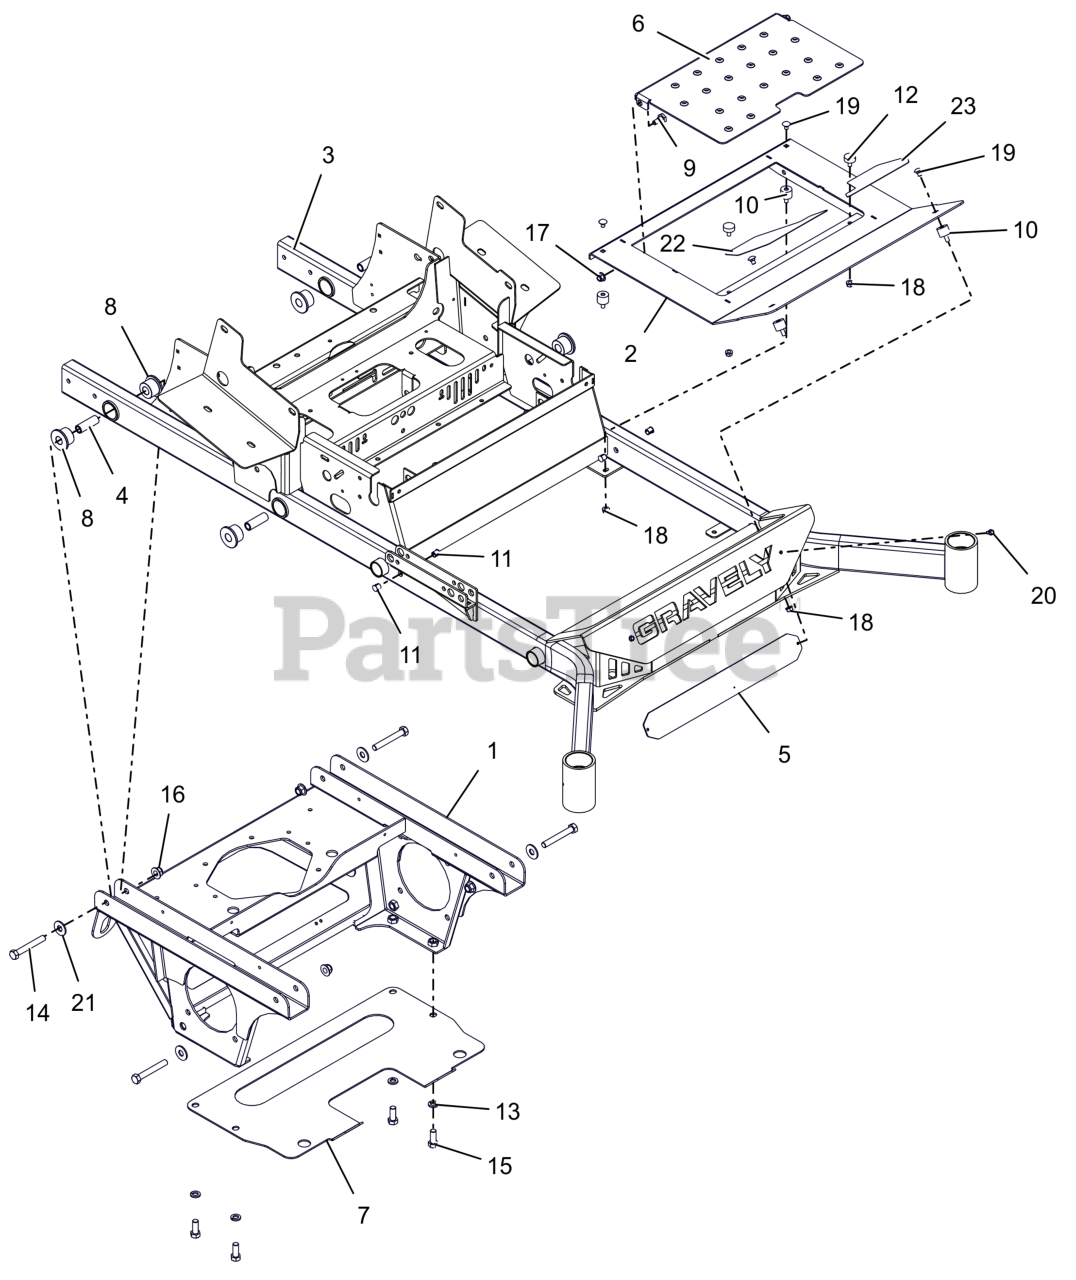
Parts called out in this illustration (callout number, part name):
1	PT200/400 AXLE/ENG FRM WMT-RED
2	FOOTPLATE WLDMT W/SAFETY DECAL
3	72" PT200/400 FRAME W/DECALS
4	BSHG-SLV .50X.75X2.23
5	BUMPER LOGO BACKING PLATE -BLK
6	INSPECTION PANEL W/SAFTY DECAL
7	PLATE-TRANSMISSION SKID
8	BSHG-FLG .75X1.51X1.13X2.0 URE
9	BLT,SHLDR EP .38-16X.30 HEX YZ
10	BUMPER,STUD MNTD W/FEMALE INSR
11	PLUG, HOLE .50
12	BUMPER, RUBBER
13	WSHR,LK-REG .500X.125 ZCC
14	BLT, HEX .50-13X3.50 G5 ZCC
15	BLT,HEX .50-13X1.25 G5 ZCC
16	NUT,NYL-FLG .50-13 GF ZCC
17	NUT,NYL-FLG .38-16 GF ZCC
18	NUT,SPNLK-FLG .31-18 G5 ZCC
19	BTL,RHSN .313-18 X 0.5 G5 ZCC
20	SCR-TAP .25-20X.50 HWH ZCC
21	WSHR,FLT .563X1.375X.109 ZCC
22	GRIP, RH FOOT PLATE
23	GRIP, LH FOOT PLATE
